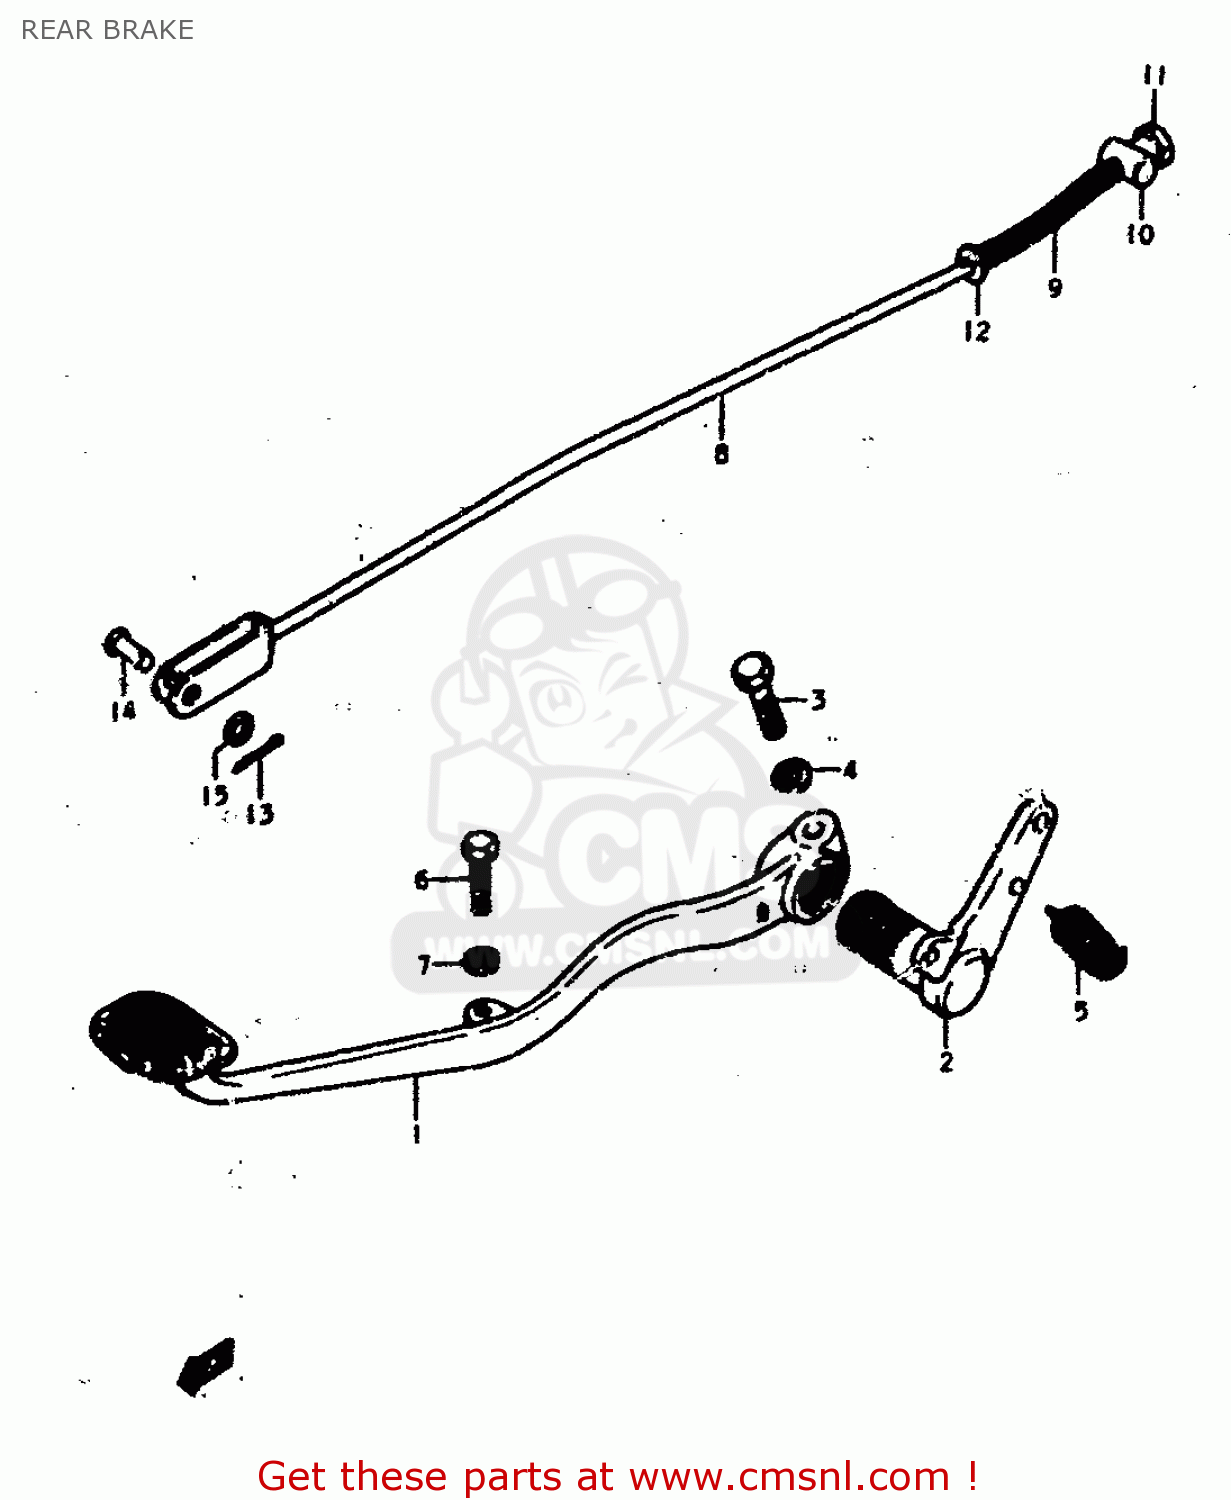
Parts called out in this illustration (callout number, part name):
1	PEDAL,BRAKE
2	ARM,BRAKE PEDAL ROD
3	BOLT
4	LOCK WASHER
5	SPRING
6	BOLT
7	NUT
8	ROD ASSEMBLY,REAR BRAKE
9	SPRING
10	PIN
11	NUT
12	WASHER
13	PIN 20X20
14	PIN(L:13.5)
15	WASHER
